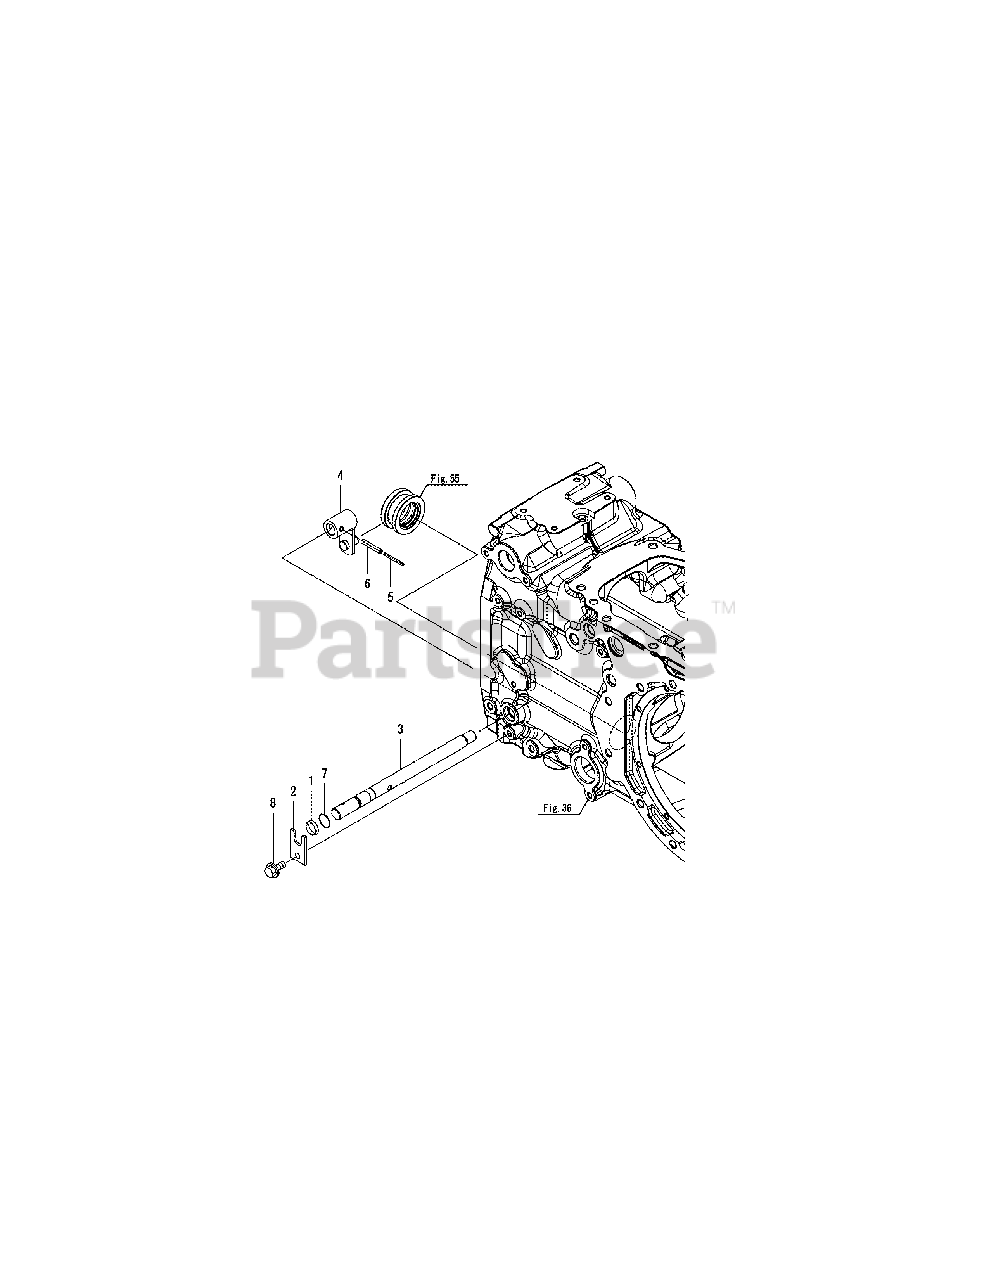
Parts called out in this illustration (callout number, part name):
4	ARM,FRONT SHIFT
5	SPRING PIN 3.5X36
6	SPRING PIN 6X36
7	O-RING 1A P-16.0
8	BOLT M 8X 16 PLATED
